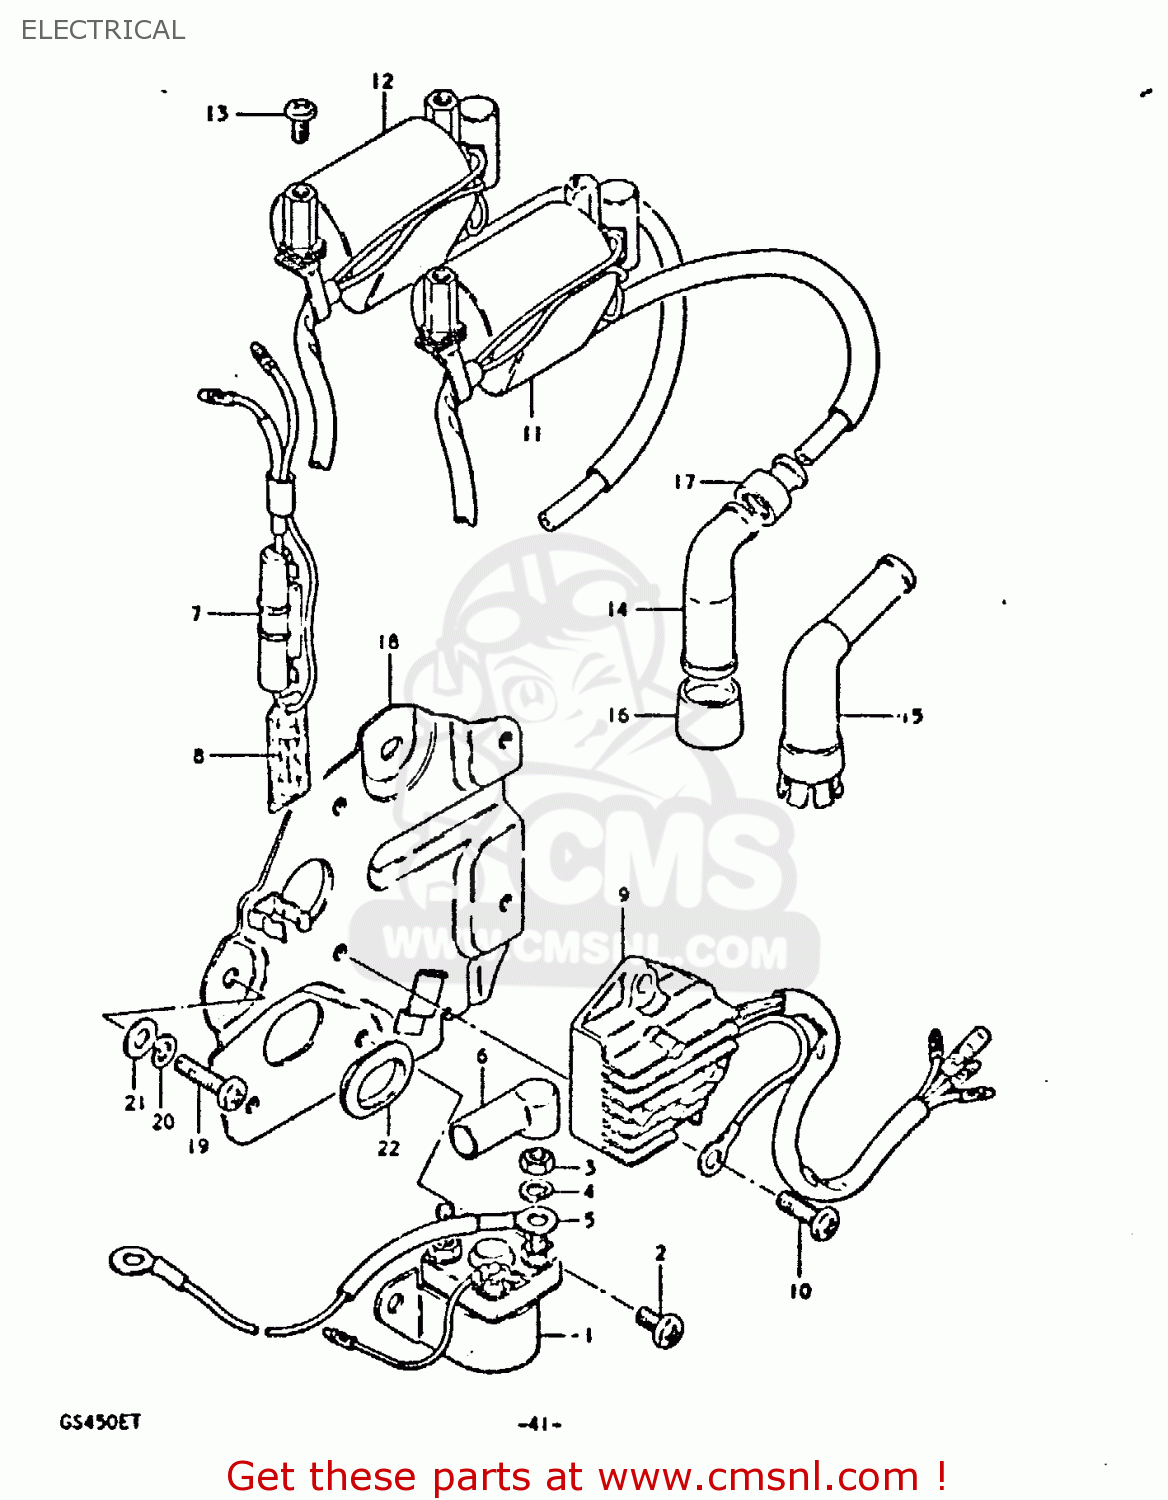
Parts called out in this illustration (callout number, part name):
1	RELAY ASSY,STARTING MOTOR
2	SCREW
3	NUT 6MM
4	LOCK WASHER
5	CORD,BATTERY MINUS
6	CAP,STARTER RELAY
7	BOX ASSEMBLY,FUSE
8	FUSE(15A)
9	RECTIFIER ASSEMBLY
10	SCREW
11	COIL ASSEMBLY,IGNITION
12	COIL ASSEMBLY,IGNITION
13	SCREW
15	CAP, SPARK PLUG (S)
17	SEAL,SPARK PLU
18	HOLDER COMP,ELECTRONIC PARTS
19	SCREW
20	LOCK WASHER
21	WASHER
22	GROMMET
